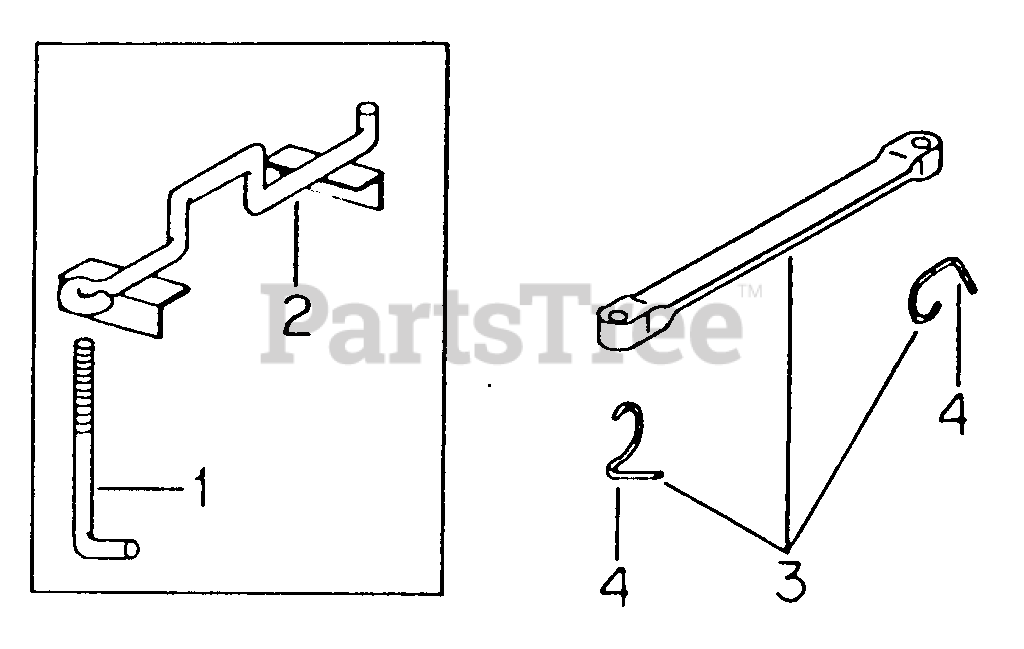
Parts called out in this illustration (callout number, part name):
1	Bolt, Battery Hold Down
2	Clamp, Battery Hold Down
3	Strap Assy, Battery
4	Hook, Battery
